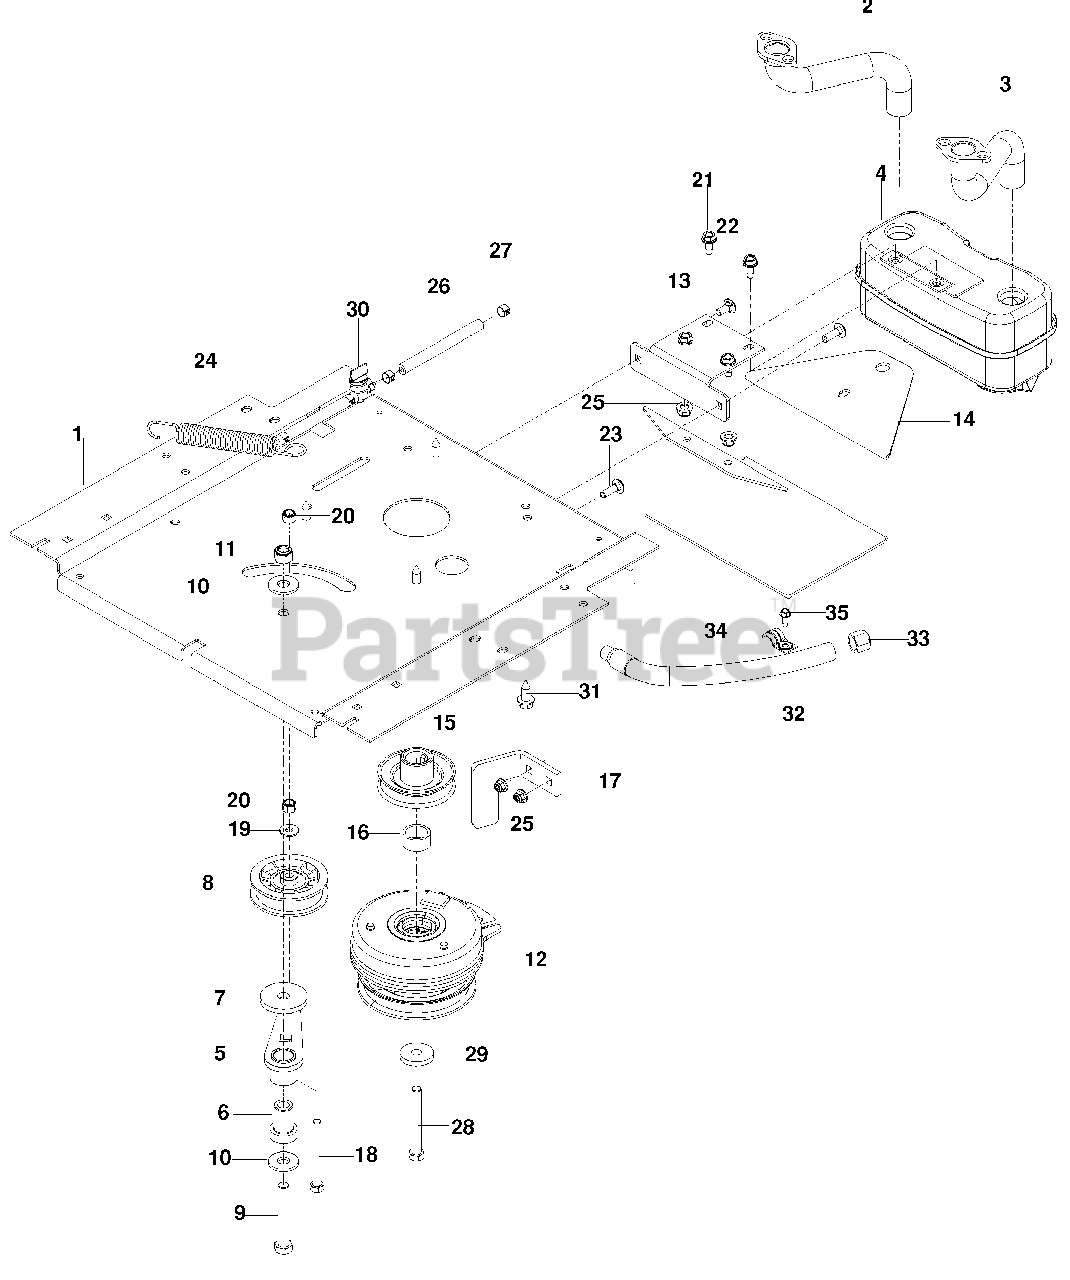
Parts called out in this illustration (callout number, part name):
1	PLATE, ENGINE
2	EXHAUST TUBE, RT
3	EXHAUST TUBE, LT
4	MUFFLER ASM TWIN
5	ARM, IDLER
6	SPINDLE, IDLER
7	WASHER, HEAVY
8	PULLEY, IDLER
9	HCS 1/2-13 x 3 1/4
10	WASHER 1/2 FLT
11	NUT 1/2-13 HEX NYLOC
13	BRACKET, MUFFLER
14	GUARD, MUFFLER
15	PULLEY, ENGINE
17	STOP, CLUTCH
18	HCS 3/8-16 x 3 1/2 TPBLT
19	WASHER 5/16 STD FLT
20	NUT 3/8-16 HEX NYLOC
21	BOLT 5/16-18 x 3/4 THD FRM
22	RHSNB 5/16-18 x 3/4
23	RHSNB 5/16-18 x 1
24	SPRING, DECK DRIVE
25	NUT 5/16-18 FLANGE NYLOC
26	FUEL LINE 5"
27	CLAMP, HOSE
28	HCS 7/16-20 x 3 1/2
29	WASHER, CLUTCH
30	VALVE, FUEL
31	HHFS 3/8-16 x 1 THD FRM
32	HOSE, DRAIN
35	SCREW 1/4-20 x 5/8 SLF TAP
